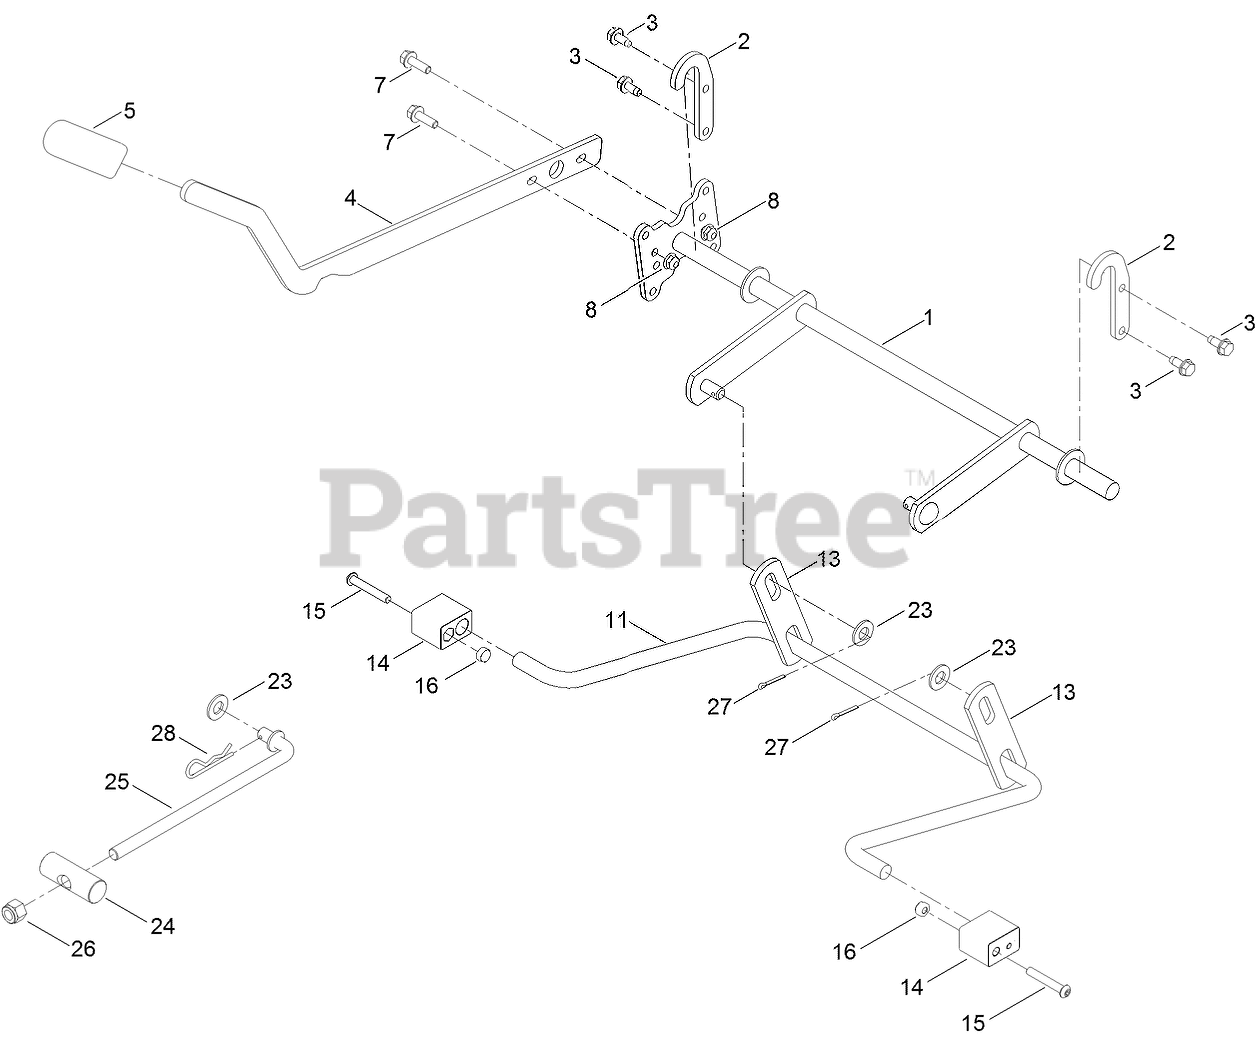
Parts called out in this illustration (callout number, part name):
1	LIFT-DECK, NARROW
2	BRACKET-LIFT
3	SCREW-HWHTF
4	LEVER-LIFT
5	GRIP-LEVER
7	SCREW-HHF
8	NUT-HF
11	ARM-LIFT, REAR
13	LINK-LIFT
14	BLOCK-PIVOT
15	SCREW-HSBH
16	NUT-HEX
23	WASHER-FLAT
24	PIN-PIVOT
25	ROD-MOUNT, DECK
26	NUT-HEX
27	PIN-COTTER
28	PIN-HAIR
